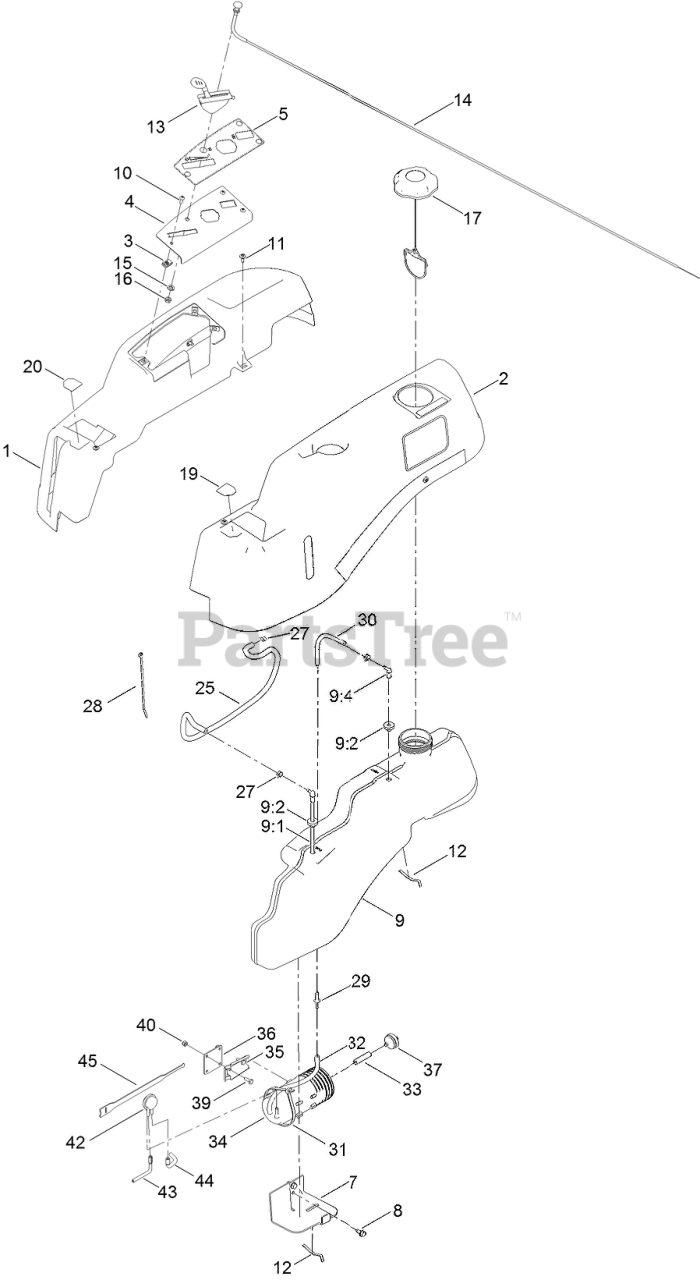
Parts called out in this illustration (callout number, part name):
1	POD-RH
4	PLATE-CONTROL
5	DECAL-PANEL, CONTROL
7	SUPPORT-TANK, FRONT
8	SCREW-HWHTF
9	FUEL TANK ASM
9:1	CONNECTOR-ELBOW, 90 DEG
9:2	BUSHING
9:4	FITTING-PLASTIC
10	SCREW-PRH
11	SCREW-SHOULDER
12	SPRING
13	CABLE-THROTTLE
14	CABLE-CHOKE
15	WASHER-LOCK
16	NUT-HJ
17	CAP-FUEL, RATCHETING
19	DECAL-LEVER, CONTROL (LH)
20	DECAL-LEVER, CONTROL (RH)
25	HOSE-FUEL
27	CLAMP-HOSE
28	TIE-CABLE
29	ADAPTOR-ORIFICE
30	HOSE-FUEL
31	TIE-CABLE
32	HOSE-FUEL
33	HOSE-FUEL
34	CANISTER-CARBON, 800CC
35	BRACKET-CANISTER, CARBON
36	PLATE-ADAPTER
37	FILTER-FUEL, INLINE
39	SCREW-HH
40	NUT-LOCK, NI
42	VALVE-CONTROL, VACUUM
43	HOSE-VENT, FORMED
44	HOSE-VENT, FORMED
45	STRAP-VELCRO, CABLE TIE
